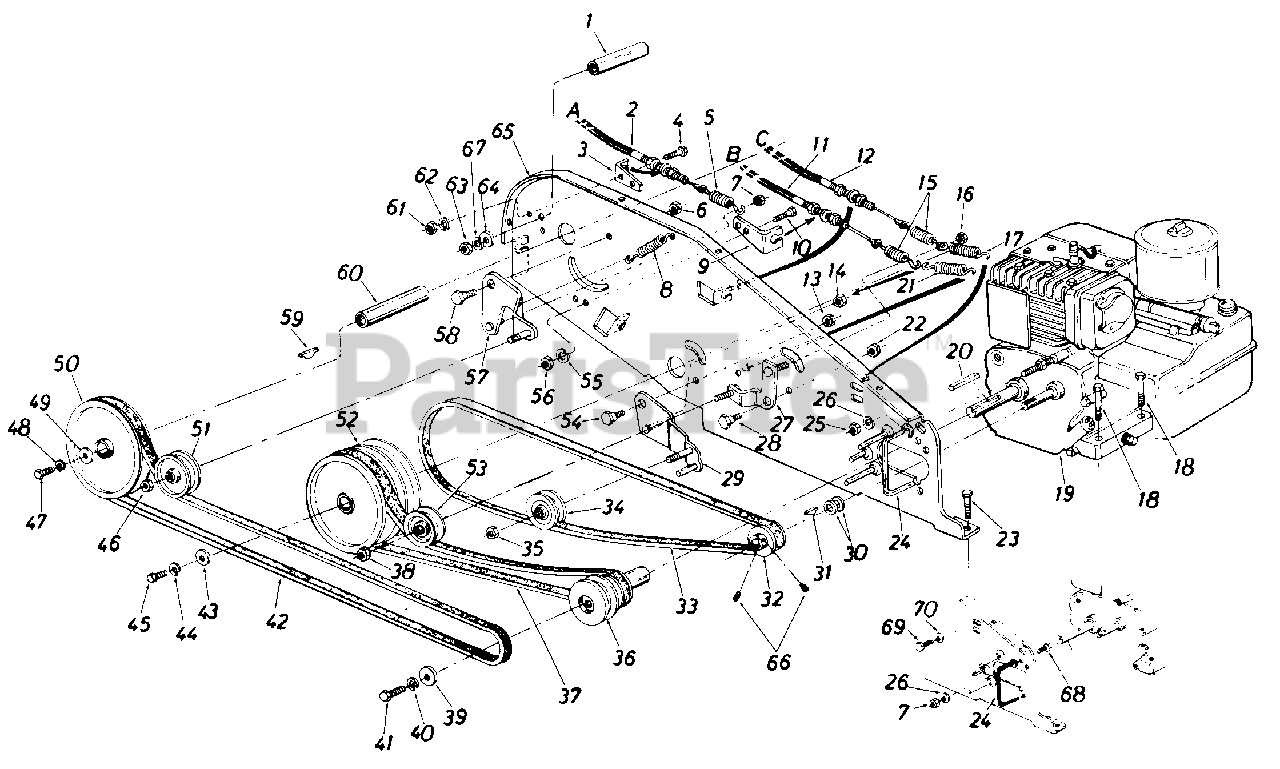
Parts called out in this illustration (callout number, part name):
1	Spacer .375" I.D. x .500" O.D. x 2.00" Lg.
2	Clutch Control Cable
3	Clutch Cable Bracket
4	Hex Bolt 5/16-18 x .75" Lg.*
5	Extension Spring .50" O.D. x 2.50" Lg.
6	Hex Cent. L-Nut 3/8-16 Thd.
7	Hex Nut 1/4-20 Thd.
8	Extension Spring .50" O.D. x 1.55" Lg.
9	Clutch Cable Bracket
10	Hex Bolt 5/16-18 x .75" Lg.
11	Clutch Control Cable 42" Lg.
12	Clutch Control Cable 41" Lg.
13	Hex Cent. L-Nut 3/8-16 Thd.
14	Hex Cent. L-Nut 1/4-20 Thd.
15	Springs
16	Hex Cent. L-Nut 1/4-20 Thd.
17	Extension Spring .41" O.D. x 2.05" Lg.
18	Hex Bolt 5/16-18 x 1.50" Lg.
19	Engine
20	Sq. Key 3/16 x 1.00 Lg.
21	Extension Spring .50" O.D. x 2.75" Lg.
22	Hex Cent. L-Nut 3/8-16 Thd.
23	Hex Bolt 5/16-18 x .75" Lg.
24	Belt Keeper
25	Hex Nut 1/4-20 Thd.
26	Bell-Wash. .265" I.D. x .75" O.D.
31	#5 Hi-Pro-Key 1/8" x 5/8" Dia.
32	1/2" V-Pulley 2.25" O.D. x .503" I.D.
33	"V"-Belt 1/2" x 43.0" Lg.
34	"V"-Belt Idler 2.62" O.D.
35	Hex Ins. L-Nut 3/8-24 Thd.
36	1/2" "V"-Pulley Ass'y.
37	"V"-Belt 1/2" x 39.0" Lg.
38	Hex Ins. L-Nut 3/8-24 Thd.
39	Fl-Wash. .344" I.D. x 1.125" O.D.
40	L-Wash. 5/16" I.D.
41	Hex Bolt 5/16-24 x 1.00" Lg.
42	"V"-Belt 1/2" x 54.0" Lg.
43	Fl-Wash. 1/4" I.D. x .93" O.D.
44	L-Wash. 1/4 I.D.
45	Hex Bolt 1/4-28 x .75" Lg.
46	Hex Ins. L-Nut 3/8-24 Thd.
47	Hex Bolt 1/4-28 x .75" Lg.
48	L-Wash. 1/4" I.D.
49	Fl-Wash. 1/4" I.D. x .93" O.D.
50	Fl-Pulley w/Flanges 6.0" O.D.
51	Fl-Idler w/Flanges 3.75" O.D.
52	Double Fl-Pulley 5/8" I.D. x 6.0" O.D.
53	Fl-Idler with Flanges 2.12" O.D.
54	Shld. Bolt .500" Dia. x .170" Lg.
55	L-Wash. 5/16" I.D.
56	Hex Nut 5/16-18 Thd.
59	#61 Hi-Pro-Key 3/16" x 518" Dia.
60	Spacer .647" I.D. x 2.75" Lg.
61	Hex Nut 5/16-18 Thd.
62	L-Wash. 5/16" I.D.
63	Hex Nut 5/16-18 Thd.
64	Fl-Wash. .406" I.D. x .750" O.D.
65	Side Plate Ass'y.
66	Set Scr. 1/4-28 x .25" Lg.
67	L-Wash. 5/16" I.D.
68	Hex Bolt 1/4-20 x 1.25" Lg.
69	Hex Bolt 5/16-24 x .62" Lg.
70	Bell-Wash. 5/16" I.D.
